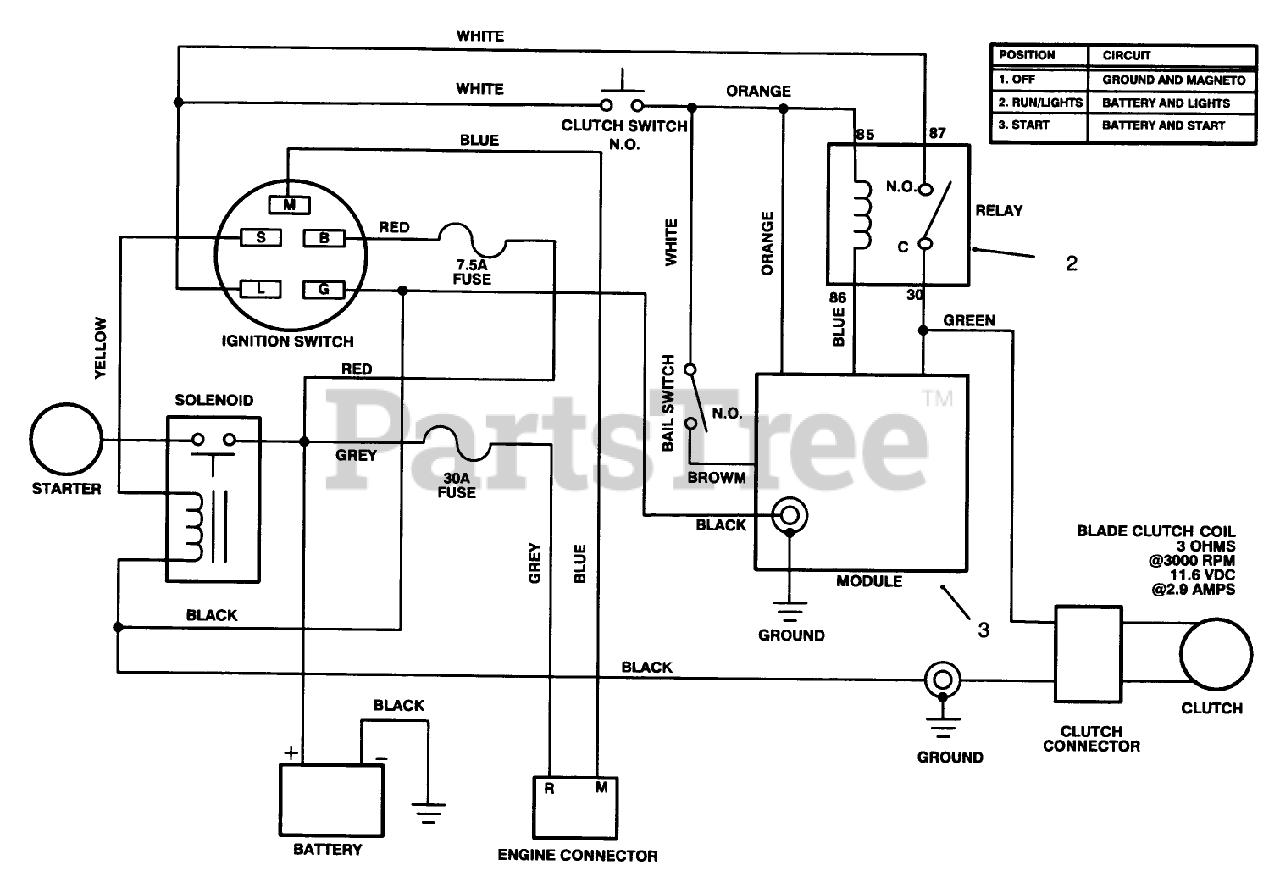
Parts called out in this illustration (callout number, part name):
1	HARNESS - WIRE
2	RELAY
3	Module
